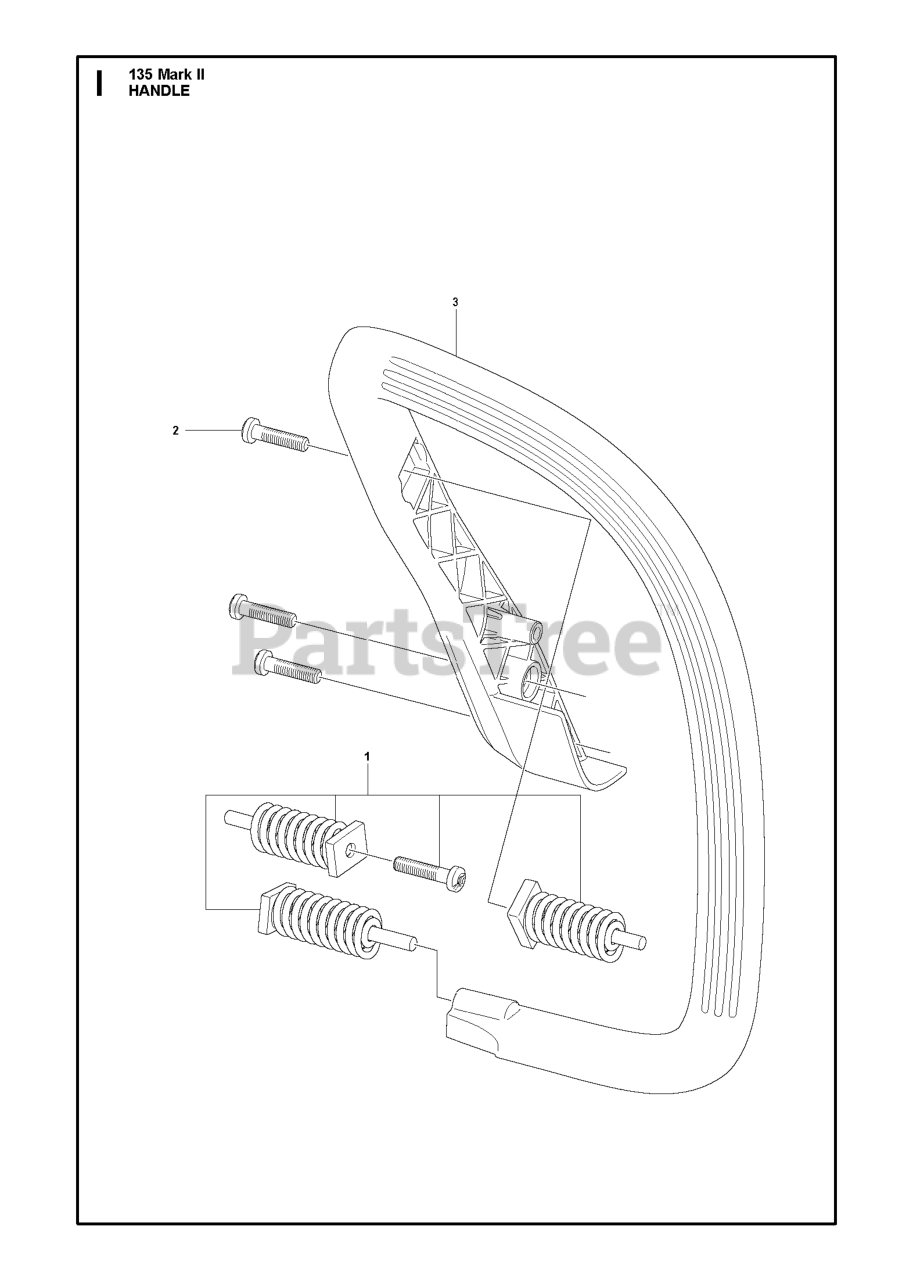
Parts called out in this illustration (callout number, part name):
1	SERVICE KIT ANTIVIBRATION ELEM
2	SCREW M5.38-14X22.225MM
3	HANDLE FRONT
